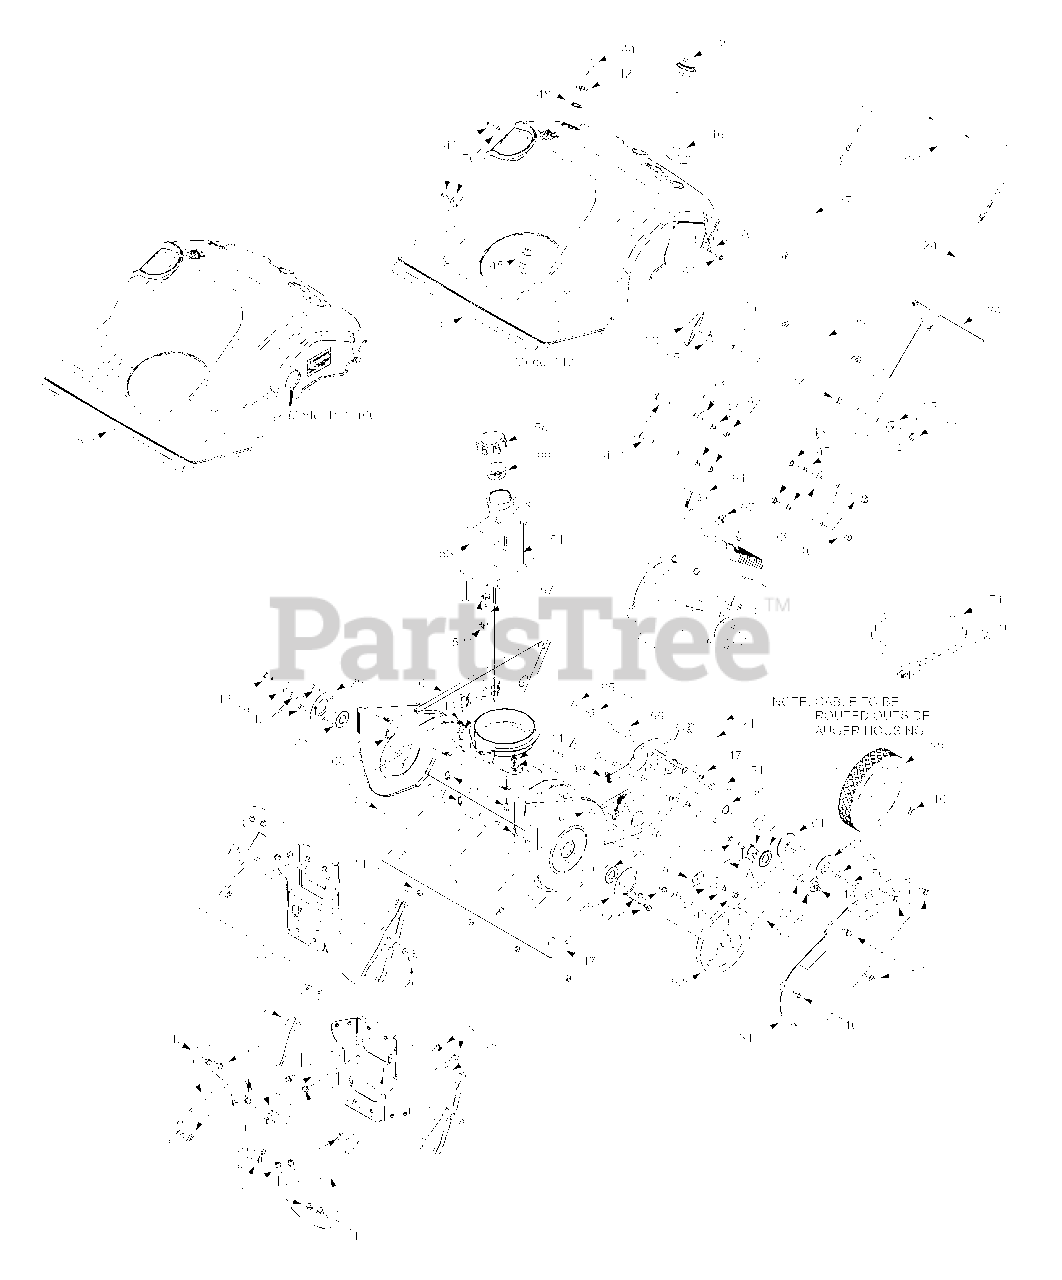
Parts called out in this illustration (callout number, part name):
1	Auger Ass'y 21" complete w/Solid Shaft
3	Hex Screw AB:1/4-14 x 0.625"
4	Rubber Spiral
5	Rubber Paddle
8	Carriage Bolt 1/2-20 x .50 LG
9	Truss Mach Scr 5/16-18 x .75
10	Hex "B" Tap Scr. 1/4-14 x .375" LG
11	Hex Screw 1/4-20 x 1.00 Gr. 5
12	Hex Tap Scr. 1/4-14 x .50" LG.
13	Hex Tap Scr. 1/4-20 x .75"
14	Hex Flange Nut, 1/4-20
15	Flat Washer .260 x .720 x .060
16	Push Cap x 1/2" Rod
17	Shave Plate 2.66 x 19.88 Double
18	Extension Spring .33 OD x 1.12 Lg.
19	Flat Washer .265 ID x .938 OD x .120
20	Flat Washer .510 ID x 1.00 OD x .125
22	Ball Bearing
23	Ball Bearing 17 x 40 x 12
24	Clutch Cable
25	Shoulder Spacer .25 THK
27	Flange Spacer
28	Belt Keeper
32	Carriage Bolt 5/16-18 x 2.0 Gr. 1
33	Handle Knob Assembly 5/16-18
34	Cable Tie
35	Saddle Washer .320 ID x .93 OD
38	Wheel-3 spoke, 7 x 1.61
39	Shroud Ass'y 3.5 HP
39	Shroud Ass'y 4.5 HP
40	Hex Flange Screw 5/16-18 x 1.50 Gr. 5
41	Hex Wash B-Tapp Scr #10-16 x .625" Lg.
42	Hex Nut 5/8-32 x .12 Special
43	Hex Nut 5/16-18 hd. Gr. 5
44	Ignition Key
45	Key Switch-Electric Start
46	Plastic Cap 1.75 Dia x .72
47	L-Wash 5/16 ID
48	L-Washer Internal .625 ID x 1.058 OD
49	Primer Button
50	Hex Screw 5/16-24 x .75 Gr. 5
51	Hex Bolt 5/16-18 x 1,50" Lg. Gr. 5
51	Hex Screw 5/16-18 x .625 Gr. 5
52	Hose Clamp
53	Cupped Washer .340 ID x .872 OD x .
54	Gas Tank Wire Support
55	Spacer .325 ID x .625 OD x .88 Lg.
56	Spacer
57	Fuel Line 17" Lg.
58	Cap-Fuel
59	Fuel Tank 2 Quart
60	V-Belt 1/2 x 35" Lg.
61	Pulley Half .625 ID x 2.35 OD
62	Pulley 1/2 V x 1/2-20 x 6.0
65	Hex Flange L-Nut 5/16-18 Gr. 5
66	Fuel Plug 1.745 Dia x .75 w/Symbol
67	Choke Lever Knob
68	H ex Scr. 1/4-15 x .50
68	Hex B-Tapp Wash Scr.#10-16 x .375
69	Flat Washer .320 ID x 1.25 OD
70	Flat Washer .194" ID x .62" OD x .063
71	Cord-Extension 2 Prong (if so equipped)
72	Flat Washer, 5/8 ID x 1.0 OD
